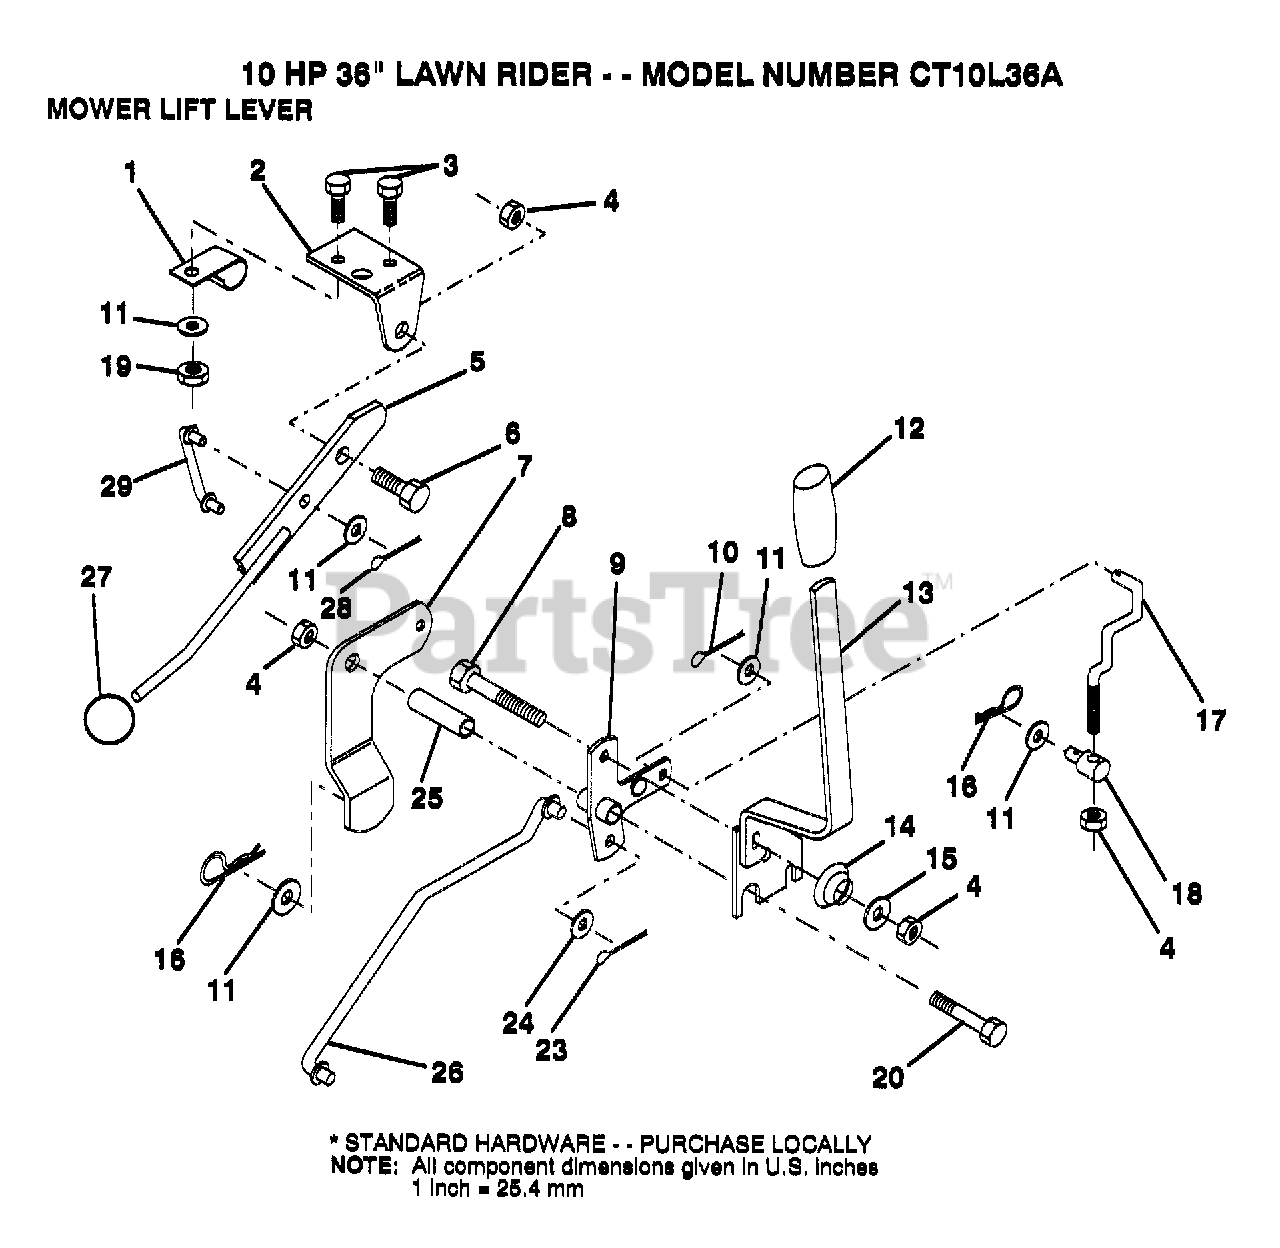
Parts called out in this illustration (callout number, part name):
1	"CLIP,INSULATOR"
2	BRKT CLUTCH
3	BOLT
5	CLUTCH LEVER AS
6	"BOLT, SHOULDER LT"
7	MOWER CLUTCH ARM
8	BOLT
9	"BELLCRANK,LIFT"
10	COTTER PIN
11	WASHER
13	"HDLE,LIFT T"
14	SPRING COMPRESSIO
15	WASHER T
16	SPRING.RETAINER
17	"LINK,LIFT FRT"
18	TRUNION
20	BOLT
23	PIN COTTER 1/8
25	TUBE SPACER
26	"ROD,MOWER LIFT "
27	GRIP CRT
29	"LINK,MOWER LIFT"
